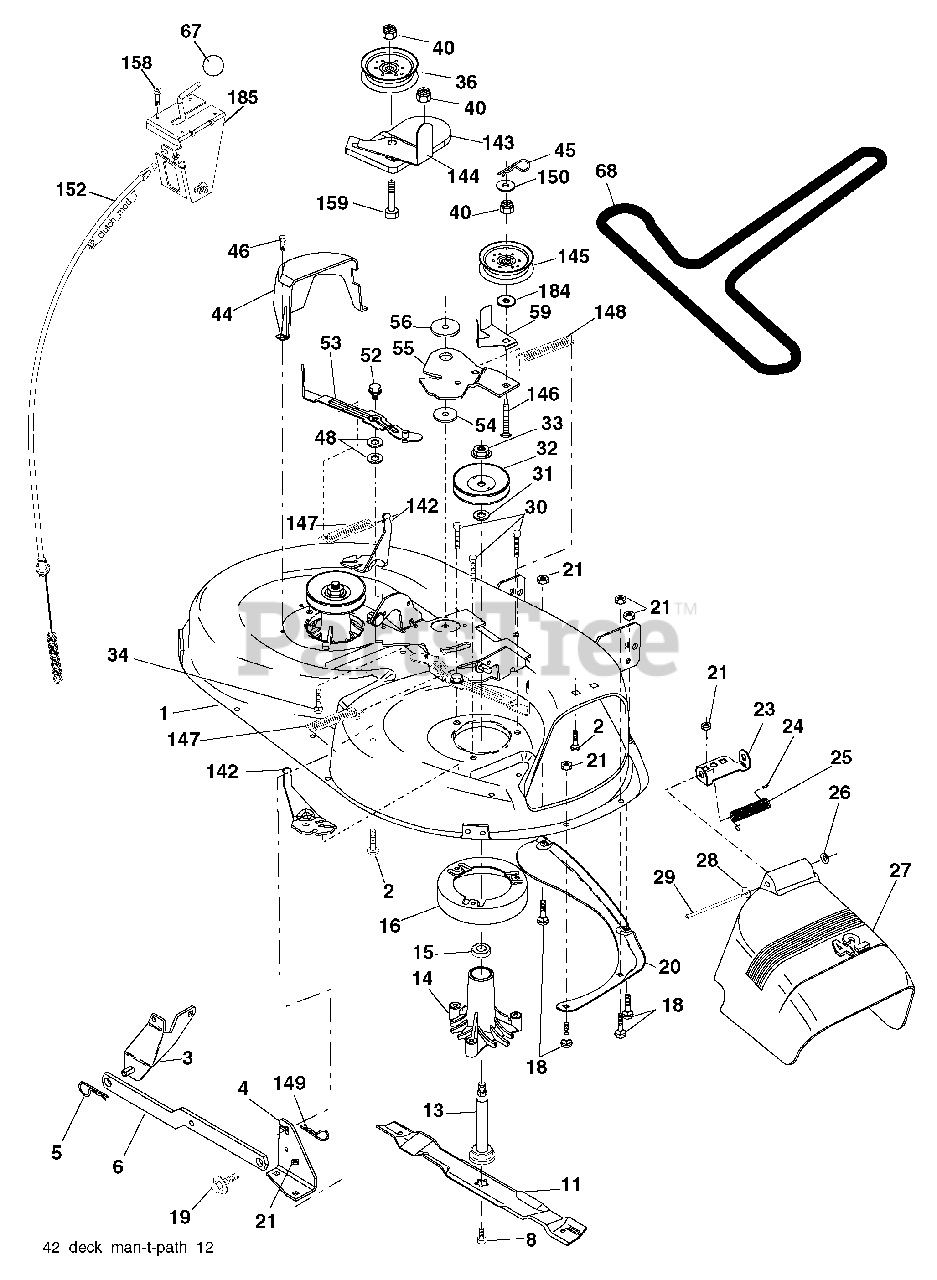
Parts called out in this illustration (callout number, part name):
1	Mower Deck Assembly, 42"
2	Bolt
3	Bracket Asm Fr. Sway Bar 3/42
4	Bracket Asm Deck 42" Sway Bar
5	Retainer Spring
6	Bar Sway Deck
8	Bolt/Washer Asm. 7/16-20 unf (The following Blades are available)
11	Blade Mower 42” Hi-Lift (for bagging and discharging)
11	Blade, Mulching 42” Std (for mulching mowers only)
11	Blade Mulching 42” Premium (For better wear when mulching)
13	Shaft As m. MNDRL
14	Housing, Mandrel, Vented
15	Bearing, Ball, Mandrel
16	Stripper, Mandrel Deck
18	Bolt, Carriage 5/16-18 x 5/8
19	Bolt, Shoulder
20	Baffle, Vortex
21	Nut
23	Bracket, Deflector Mower 42"
24	Cap, Sleeve 80 x 112 Blk Mower
25	Spring, Torsion, Deflector 2 52
26	Nut, Push Phos & Oil
27	Shield, Deflector 42" Blk
28	Washer 11/32 x 5/8 x 16 Ga.
29	Rod, Hinge 42" 6 75 W/G
30	Screw Thdrol
31	Washer, Spacer Mower Vented
32	Pulley, Mandrel
33	Nut, Toplock
34	Bolt Carr SH 3/8-16 x 1-1/2 Gr. 5
36	Pulley, Idler, Flat
40	Nut Lock 3/8-16
44	Guard, Mandrel, LH
45	Retainer
46	Screw, Thdrol 1/4-20 x 5/8 T
48	Washer, Hardened
52	Bolt, Shoulder 5/16-18 unc
53	Arm Assembly, Pad, Brake
54	Washer, Hardened
55	Arm, Idler
56	Spacer, Retainer
59	Guard TUV Idler
67	Knob Round
68	V-Belt, 42" Mower
142	Arm Spring Brake Mower
143	Bracket Arm Idler 42"
144	Keeper Belt 42" Clutch Cable
145	Pulley Idler Flat
146	Bolt Carriage Idler
147	Spring Extension
148	Spring Return Idler
149	Retainer Spring Yellow
150	Washer 9/32 x 3/4 x 10 Ga.
152	Clutch Cable 42"
158	Screw Hex Thd Cut 1/4-20 x 1/2
159	Bolt Rdhd Sqn 3/8-16 unc x 1-3/4
184	Washer 13/32 x 7/8 x 10 Ga.
185	Head Asm Cable Clutch
185	Mandrel Assembly
185	Replacement Mower, Complete
